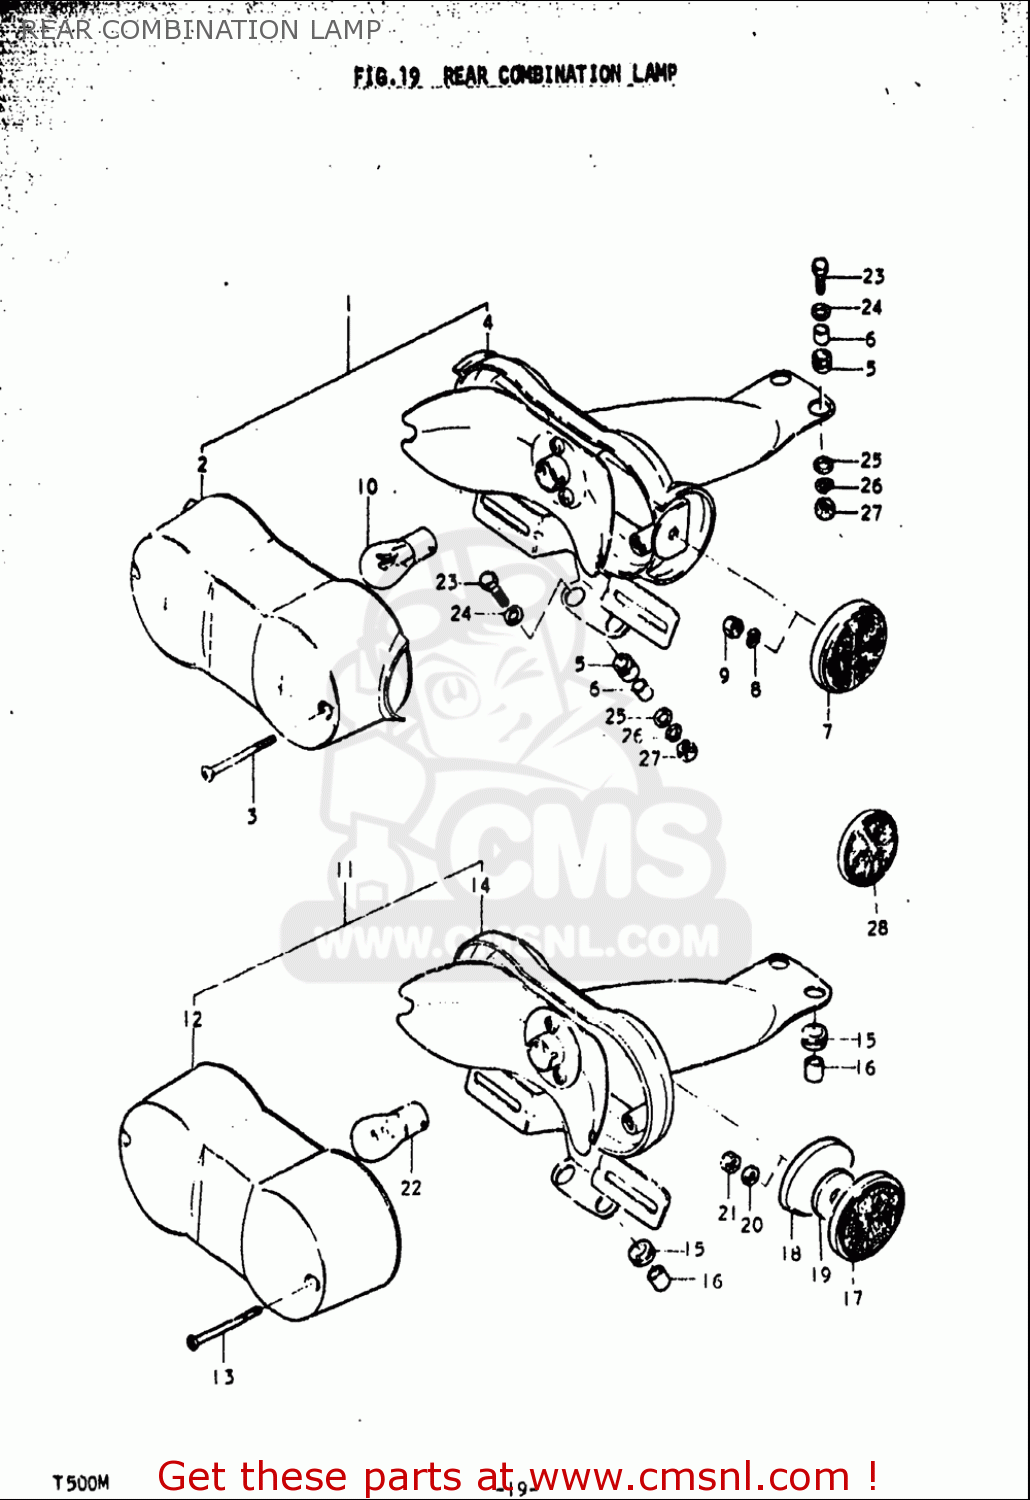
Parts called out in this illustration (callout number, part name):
2	LENS,RR COMBINATION LAMP
3	SCREW
5	CUSHION
6	SPACER
8	WASHER,LOCK
9	NUT
10	BULB(12V23W)
12	LENS,RR COMBINATION LAMP
13	SCREW
14	HOUSING,RR COMBINATION LAMP
15	CUSHION
16	SPACER
19	WASHER(5.5X18X1)
20	WASHER,LOCK
21	NUT
22	BULB 12V35/35W
23	BOLT 6X23
24	WASHER(6.5X20X1.6)
25	WASHER
26	WASHER,LOCK
27	NUT
